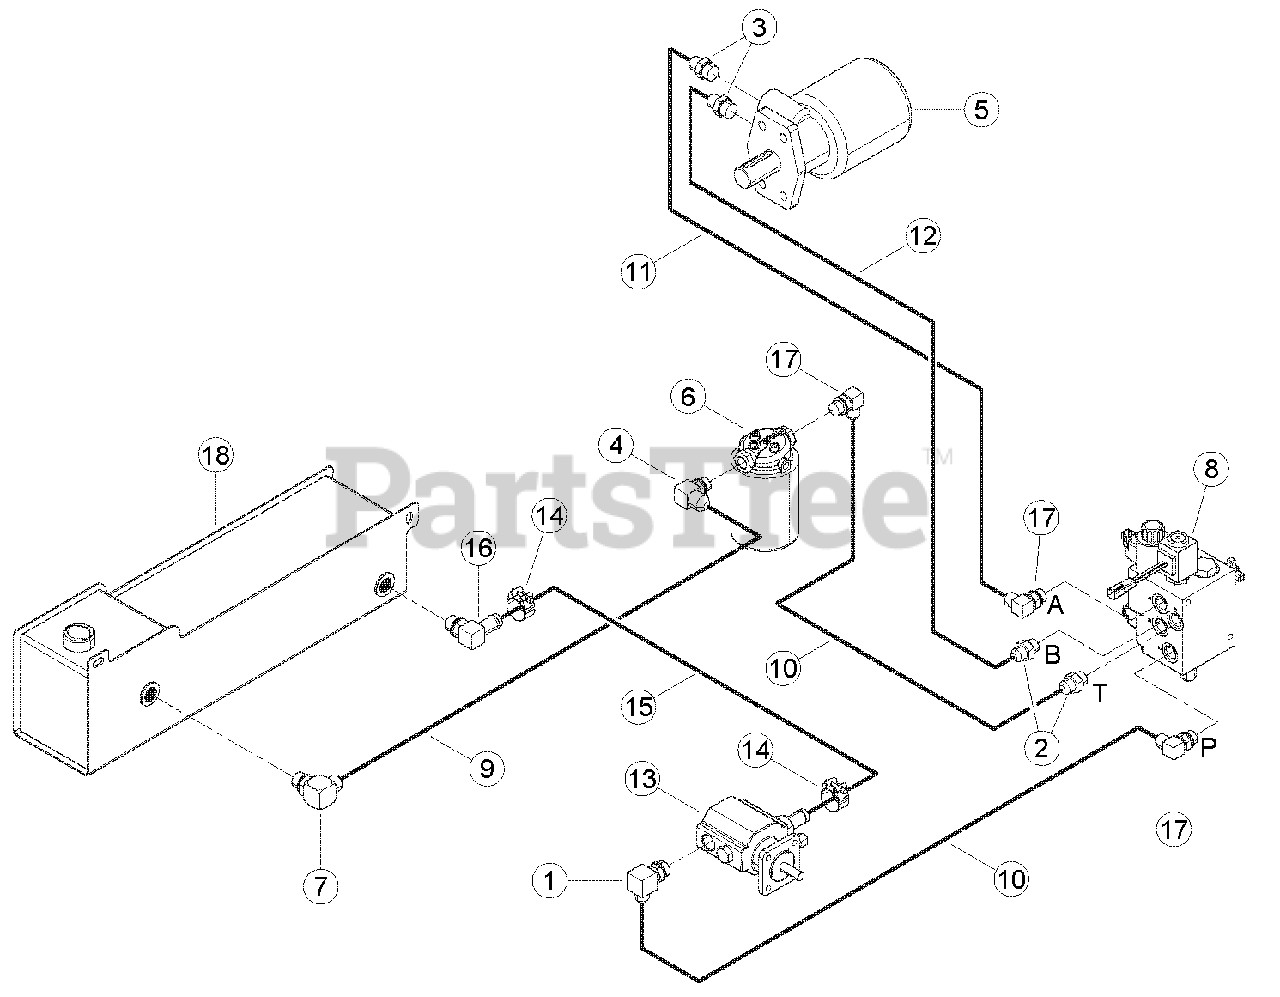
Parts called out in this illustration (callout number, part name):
1	ADAPTER, -10 MORING / -8 MJIC 90 DEG.
2	ADAPTER, -8 MORING / -8 MJIC
3	ADAPTER, -10 MORING / -8 MJIC
4	ADAPTER, -8 MORING / -8 MJIC 90 DEG.
5	MOTOR, 45 CU. IN. HYDRAULIC
6	FILTER, SPIN-ON
7	ADAPTER, -10 MORING / -10 MJIC 90 DEG.
8	ASSEMBLY, SA - 1987 VALVE
9	HOSE ASSEMBLY, -10 FMJIC / -10 FMJIC LD 90 X 21"
10	HOSE ASSEMBLY, -8 FMJIC / -8 FMJIC 90 X 21"
11	HOSE ASSEMBLY, -8 FMJIC / -8 FMJIC 90 X 61"
12	HOSE ASSEMBLY, -8 FMJIC / -8 FMJIC X 61"
13	PUMP, PB CW HI/LO .646 DISP.
14	CLAMP, 1" OD. HOSE T-BOLT
15	HOSE, .75 ID. X 24" 100R4 HYD.
16	ADAPTER, -10 MORING / .75 90 BEAD HOSE
17	ADAPTER, -8 MORING / -8 MJIC 90 DEG.
18	WELDMENT, HYDRAULIC TANK
